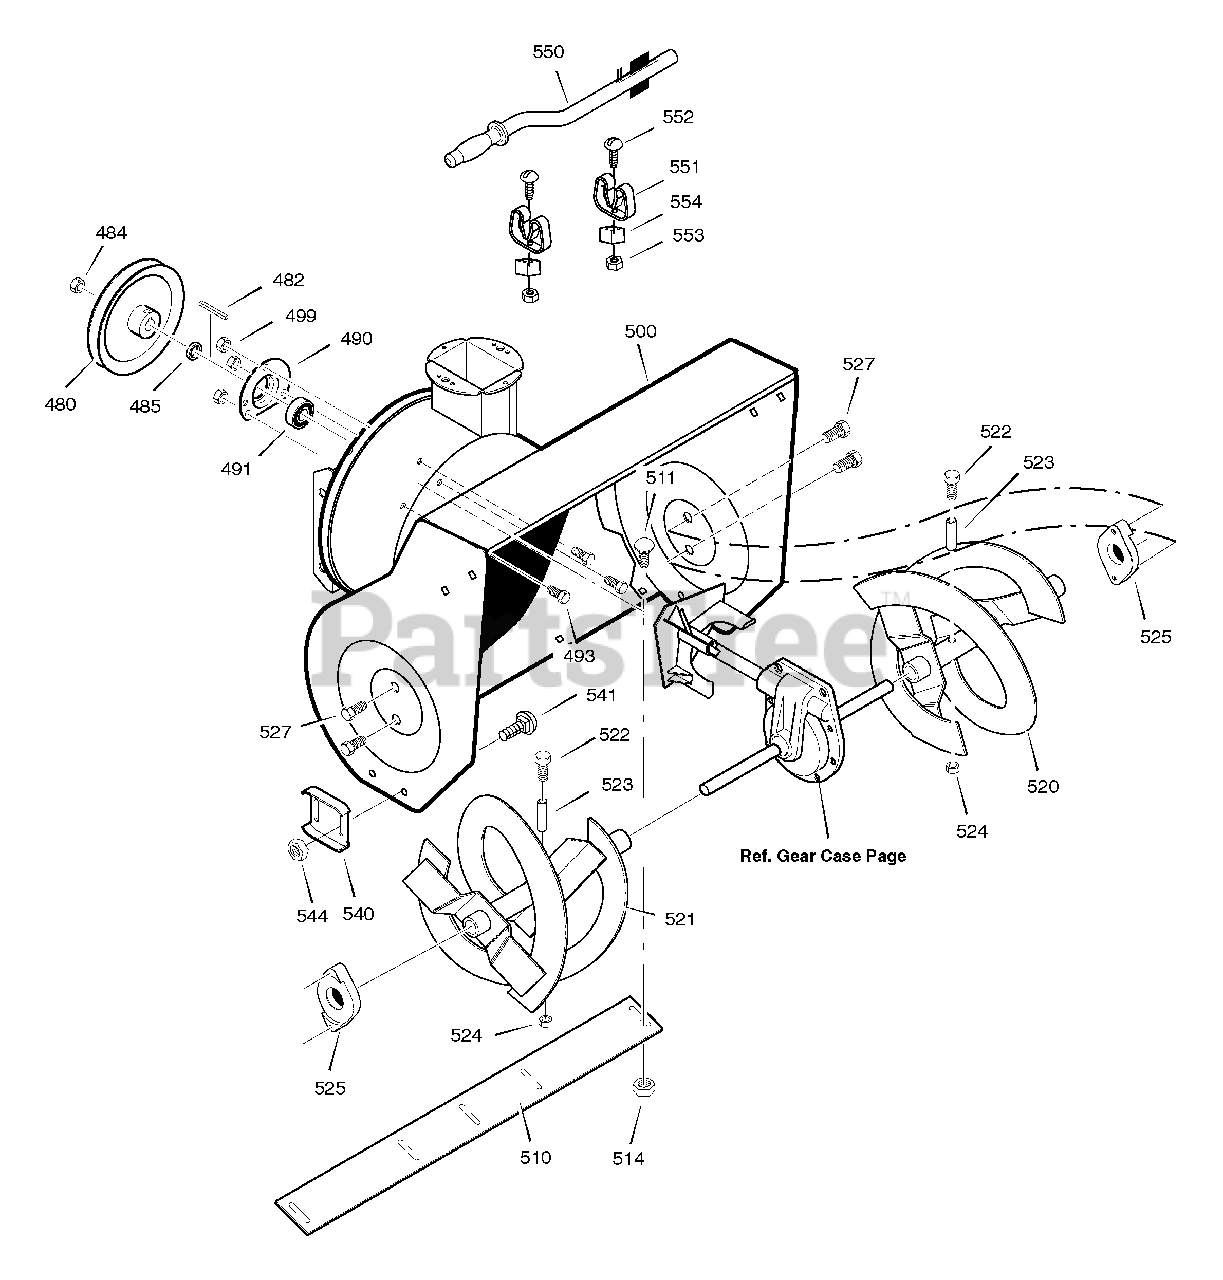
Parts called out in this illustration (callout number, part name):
480	PULLEY, 4L 8.40 OD
482	KEY, SQUARE 3/16 X 3/4
484	NUT, 1/2-20
485	SPACER, FRICTION PULLEY
490	RETAINER, BALL BRNG
491	BEARING, BALL
493	BOLT, HEX 5/16-18X .50
499	NUT, 5/16-18 HEXWDFLLK
500	HOUSING, ASSY
510	BLADE, SCRAPER
511	BOLT, 5/16-18X.75
514	NUT, 5/16-18
520	AUGER, ASSY, LH
521	AUGER, ASSY, RH
522	SCREW, 1/4-20 X 1.75
523	SPACER, SLEEVE
524	NUT, 1/4-20
525	BEARING, FLANGE
527	SCREW, 5/16-18 x 0.75
540	SKID, HEIGHT ADJUST
541	BOLT, 5/16-18 X .75
544	NUT, 5/16-18
550	BRUSH, CLEANOUT
551	CLIP, RETAINER
552	SCREW
553	NUT
